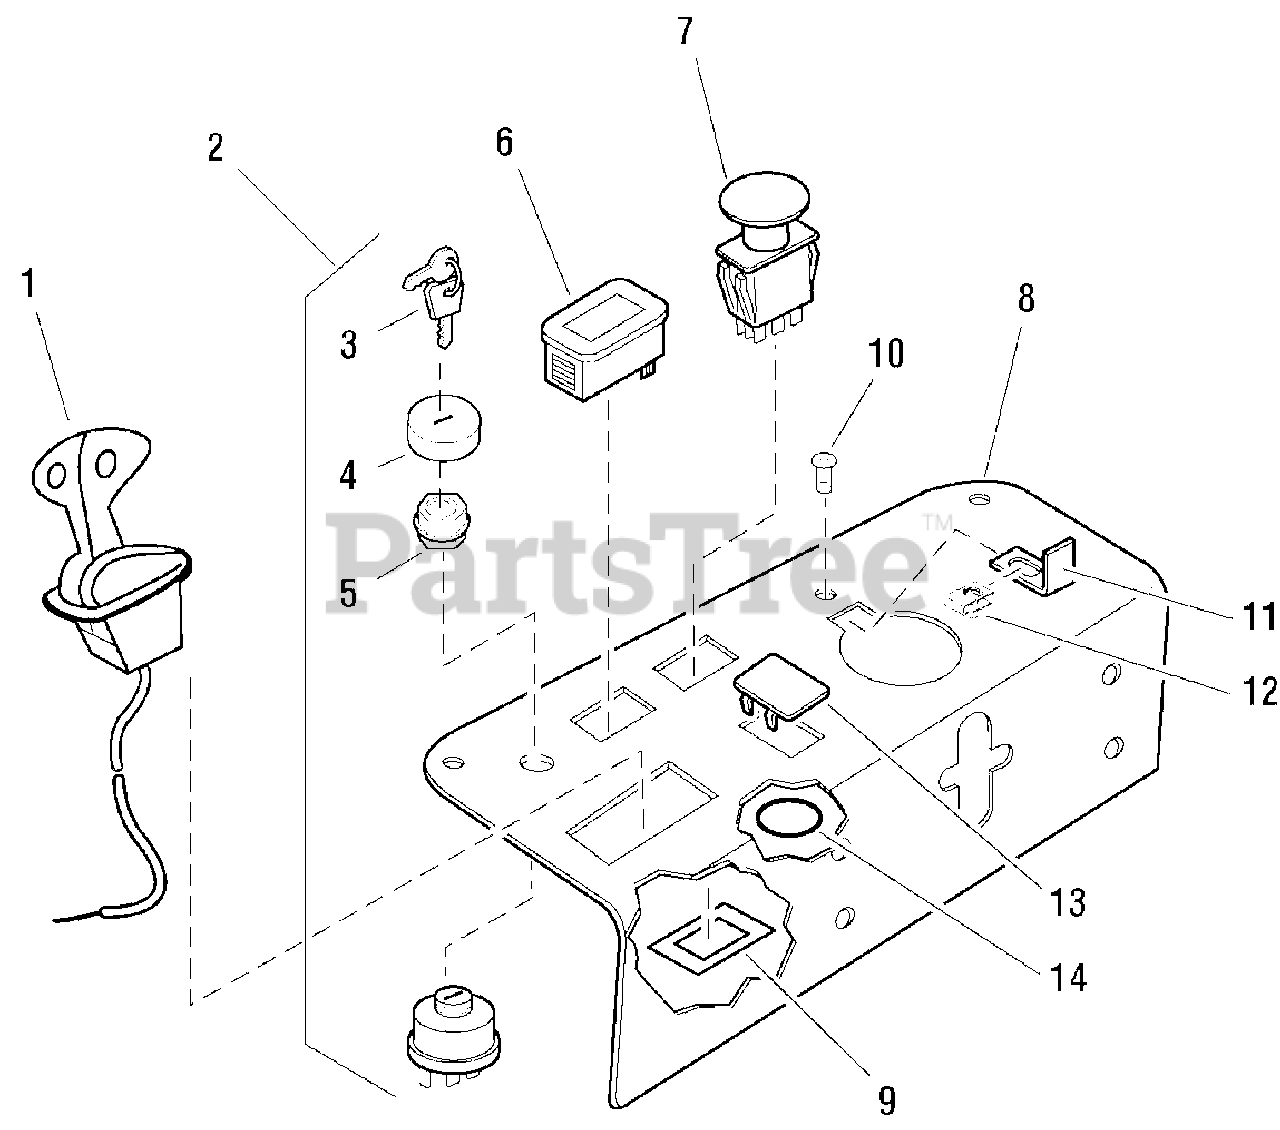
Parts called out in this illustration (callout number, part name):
1	DUAL CHOKE/THROTTLE LEVER
2	SWITCH, IGNITION, 6 POST
3	KEY, Ignition Molded (Set of 2)
4	COVER, PLASTIC, SNAP ON
5	PLASTIC NUT
6	HOUR METER, DIGITAL (Includes Retaining Ring)
7	SWITCH, PTO
8	CONTROL PANEL
9	RING, SWITCH RETAINER
10	CAPSCREW, BUTTON ALLEN HEAD, 1/4-20 x 3/4
11	LOCK BRACKET
12	BODY CLIP, 1/4-20
13	HOLE PLUG
14	O-RING
